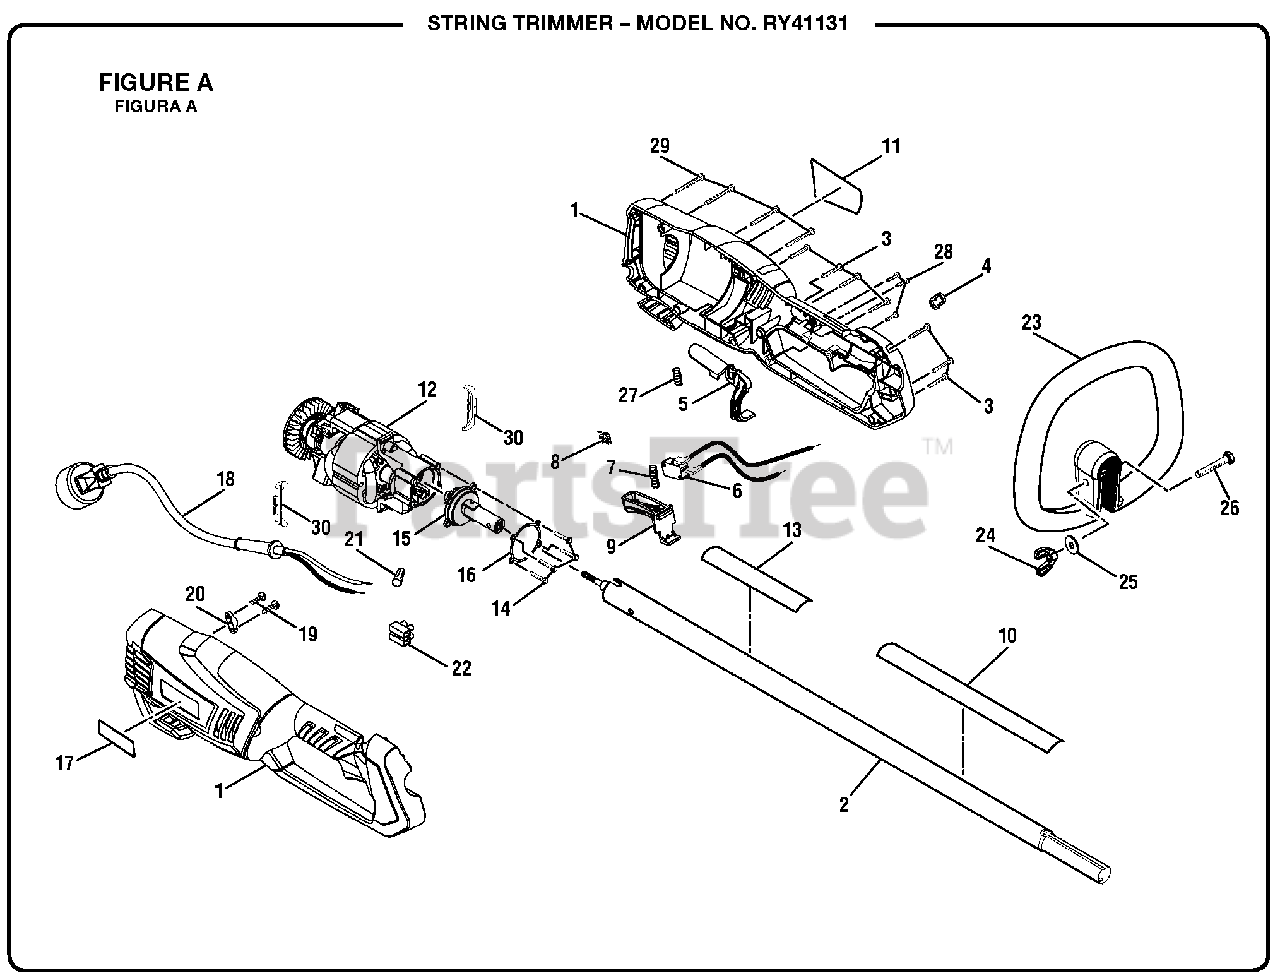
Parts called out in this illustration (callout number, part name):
1	Housing Assembly
2	Boom Assembly (Incl. Key Nos. 10 and 13)
3	Screw (M4 x 14 mm)
4	Strap Hook
5	Lock-Out Lever
6	Switch Assembly w/Leads
7	Compression Spring
8	Torsion Spring
9	Switch Trigger
10	Warning Label (French and Spanish)
11	Data Label/Warning Label (English)
12	Motor Assembly
13	Icon Strip Label
14	Screw (M4 x 10 mm)
15	Gear Assembly
16	Rubber Gasket
18	Power Cord Assembly
19	Screw (M3.5 x 12 mm)
20	Cord Clamp
22	Terminal Block
23	Front Handle Assembly (Inc. Key Nos. 24-26)
24	Wing Nut (1/4-20)
25	Washer (1/4 in.)
26	Bolt (1/4-20 x 40 mm)
27	Compression Spring
28	Screw (M2.9 x 10 mm)
29	Screw (M4 x 18 mm)
30	Motor Mount
